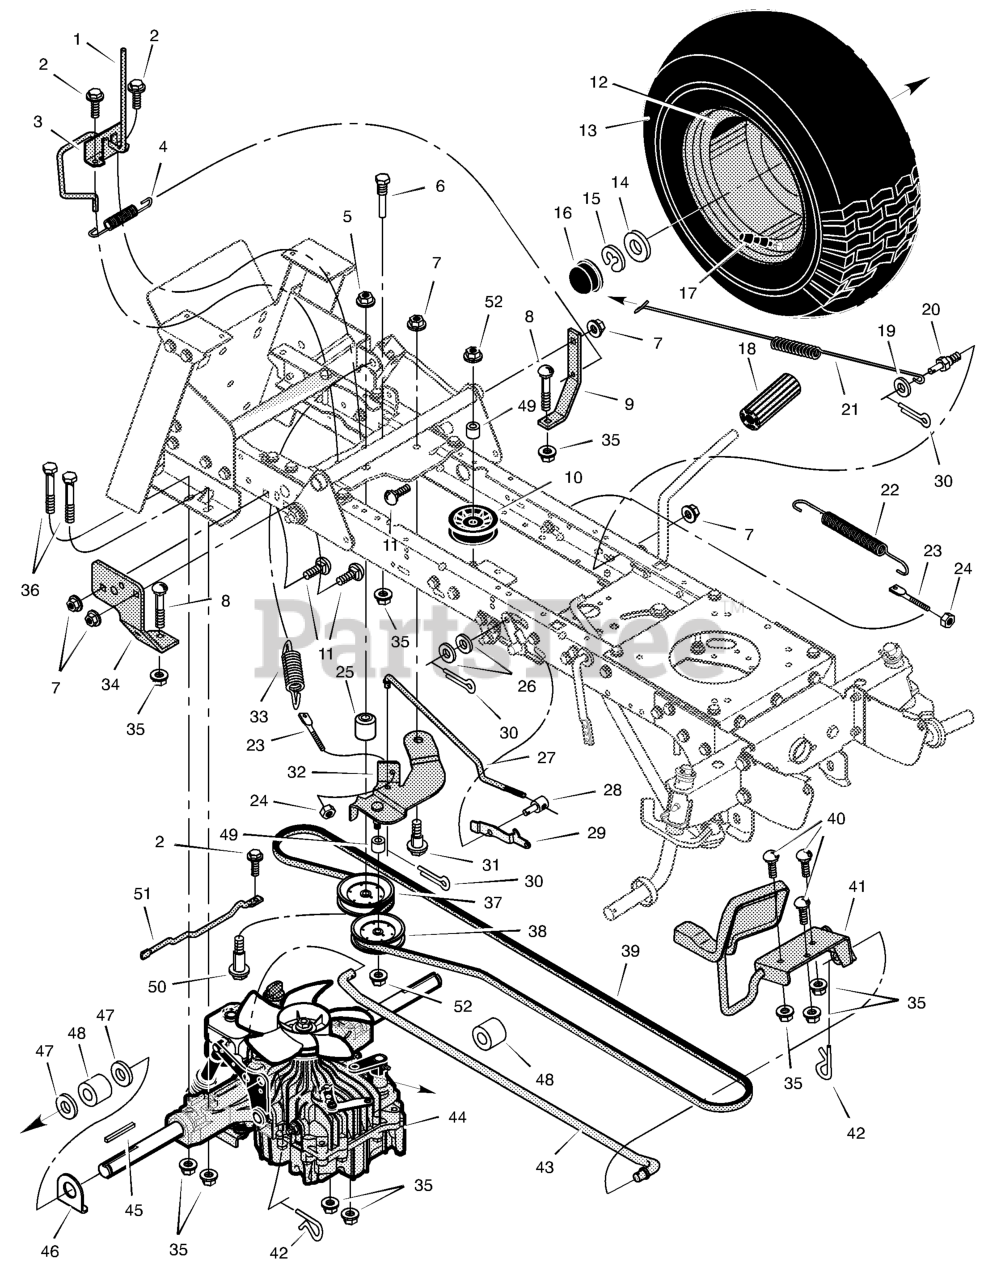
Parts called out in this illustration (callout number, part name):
1	Rod, Cable
3	Bracket, Cable
4	Spring, Extension
5	Locknut
6	Guide, Belt
7	Locknut
8	Bolt, Carriage
9	Bracket, Torque
10	Pulley, Idler
11	Bolt, Carriage
12	Assembly, Wheel and Tire
13	Tire Only *
16	Cap, Hub
17	Stem, Valve
18	Pedal
19	Washer
20	Stud, Threaded
21	Spring, Extension
22	Spring - Extension
23	Stud, Spring Mount
24	Locknut, Flange
25	Spacer
27	Rod, Clutch
28	Nut, Adjusting
29	Latch, Parking Brake
30	Pin, Cotter
31	Bolt, Shoulder
32	Assembly, Idler Arm
33	Spring, Extension
34	Bracket, Torque
35	Nut, Flange
36	Bolt
37	Pulley, Backside Idler
38	Pulley, V Idler
39	Belt, Drive
40	Bolt, Carriage
41	Assembly, Pedal
42	Pin, Hair
43	Rod, Hydro Control
44	Transaxle, Hydro **
45	Key, Square
46	Washer, Thrust
47	WASHER, 1-1.3 16G FLT
51	Guide, Belt
52	Locknut
